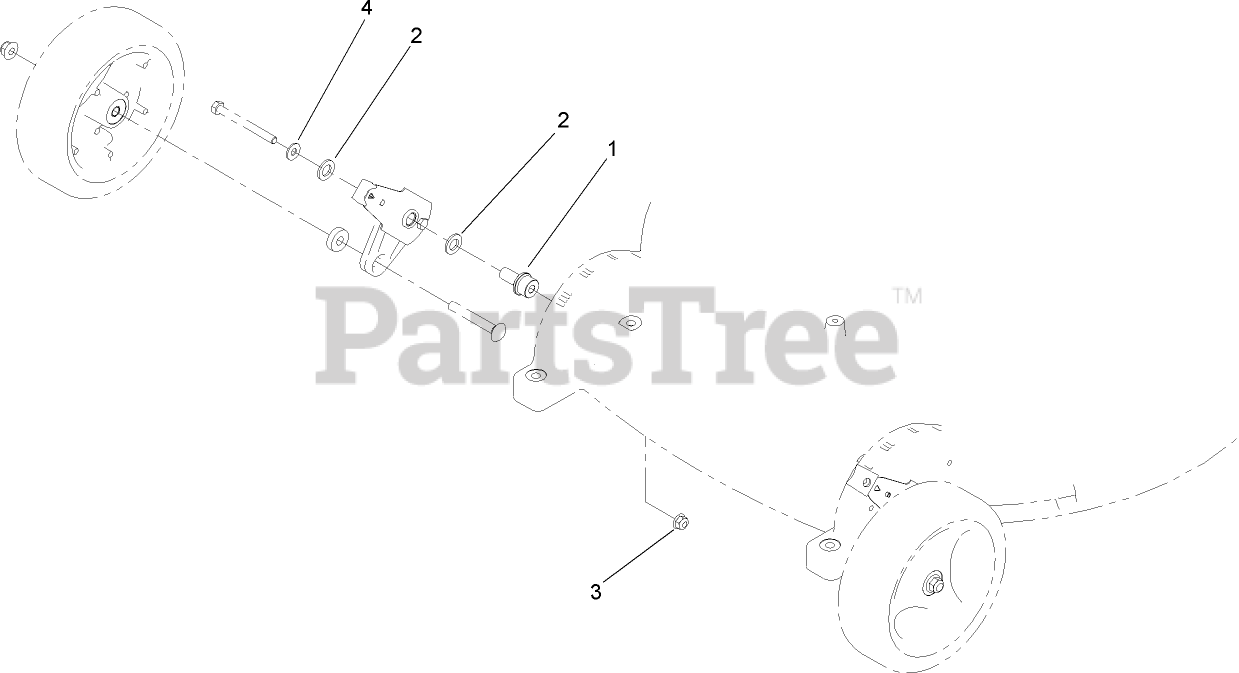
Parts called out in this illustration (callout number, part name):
1	BUSHING-PIVOT, WHEEL
2	WASHER-THRUST, NYLON
3	NUT-HF, NI
4	WASHER-FLAT
